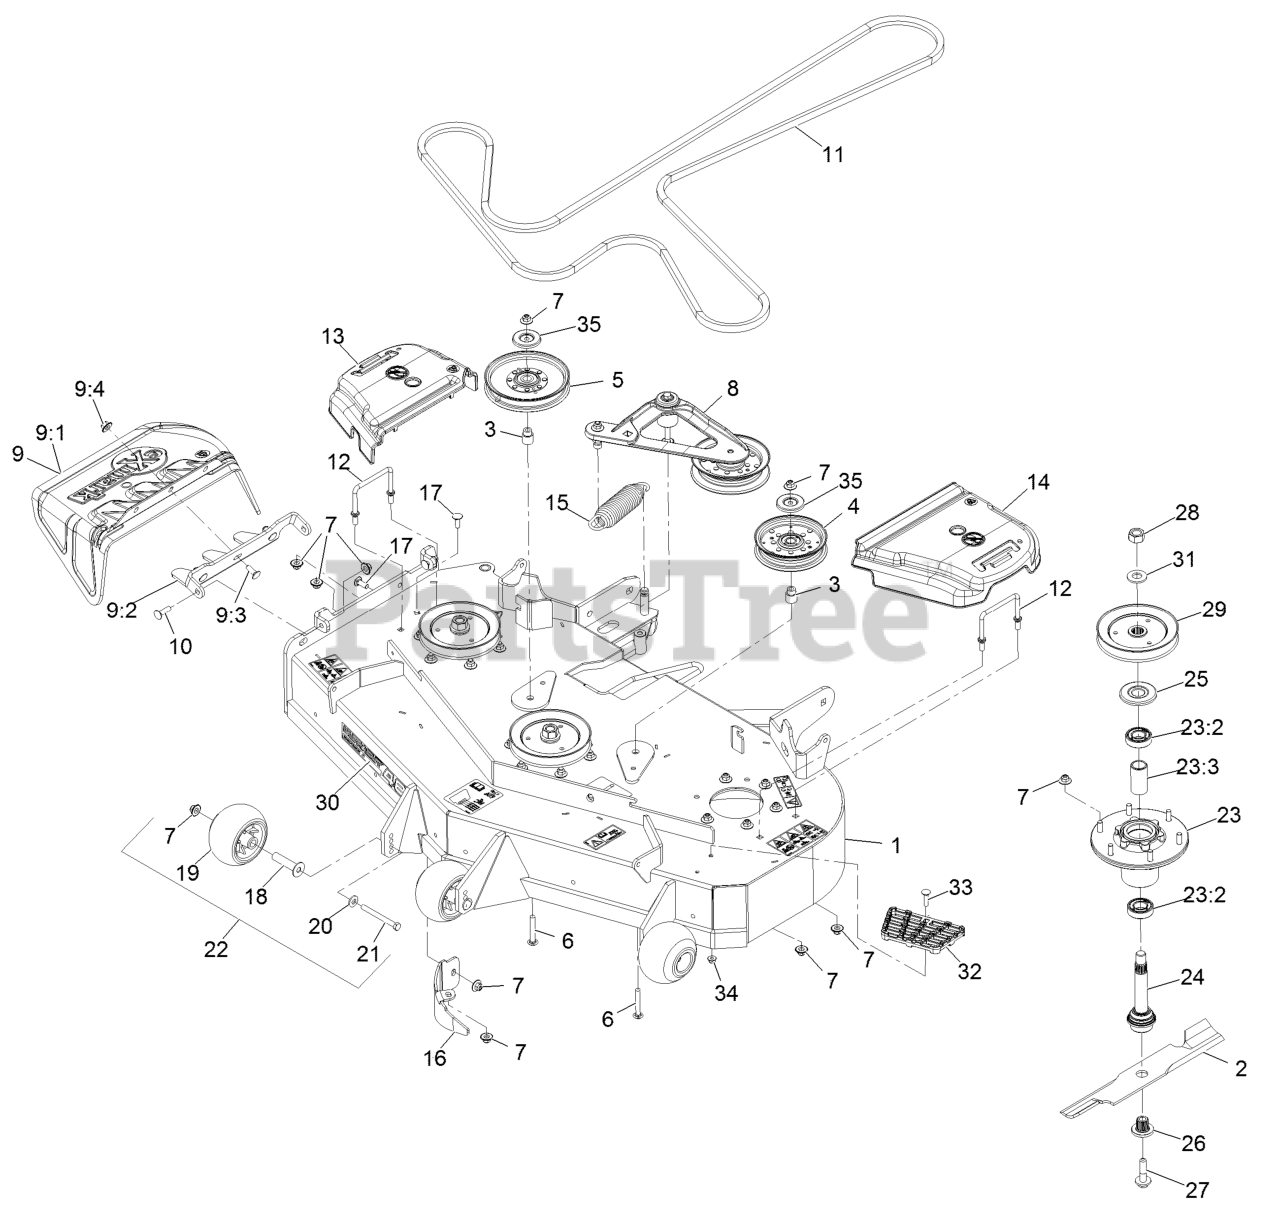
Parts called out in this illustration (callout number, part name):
1	ASM,DECK W/DECALS 48
3	BUSHING-IDLER
4	PULLEY-IDLER, FLAT
5	IDLER-PULLEY
6	SCREW-CARR
7	Nut-Nyloc 3/8-16 Flg
8	DECK IDLER ASM
9	ASM,DISCHARGE CHUTE
9:1	CHUTE,DISCHARGE
9:2	BRACKET,DISCHARGE CHUTE
9:3	SCREW-CARR
9:4	Nut-Nyloc 3/8-16 Flg
10	Bolt-Carriage 3/8-16 X 1 1/4
11	BELT
12	WIREFORM-COVER
13	COVER-BELT, RH
14	COVER-BELT, LH
15	SPRING-EXTENSION
16	BAFFLE-DOGLEG,LZS LZX VT4
17	SCREW-CARR
18	AXLE, ROLLER
19	ROLLER-SCALP, ANTI
20	WASHER-BELLEVILLE
21	SCREW-HH 3/8-16 X 3 3/4 GR 8
22	KIT, ANTI-SCALP ROLLER
23	ASM-CUTTER HSG WITH BEARINGS
23:2	BEARING-BALL
23:3	SPACER-BEARING
24	ASM-SPINDLE AND SEAL
25	GUARD,BEARING TOP .989
26	BUSHING,SPLINED
27	SCREW,SEMS 1/2-20 X 2.19
28	NUT-HEX
29	SHEAVE,BLADE DRIVE 5.90
30	Decal, 484
32	STEP-DECK
33	Bolt-Carriage 5/16-18 X 1 1/4
34	NUT-HF, NI
35	SHIELD-DUST
